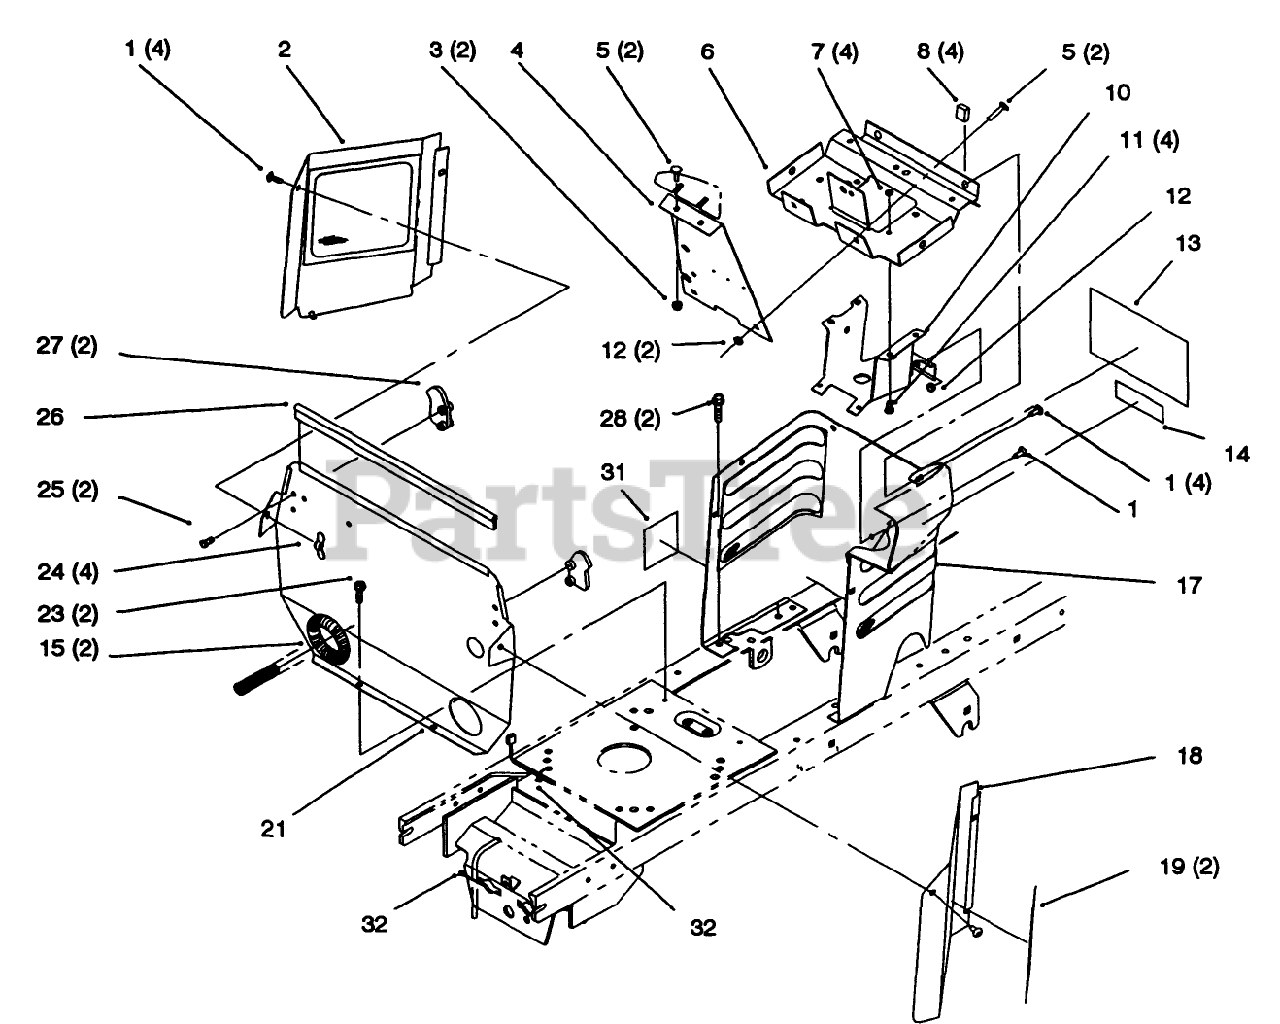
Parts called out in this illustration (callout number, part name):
1	SCREW-HH
2	RH SIDE COVER ASM
3	NUT-KEPS
4	PANEL-SUPPORT DASH
5	SCREW-CARR
6	SUPPORT-DASH
7	NUT-HEX
8	NUT RETAINER - J TYPE
10	BRACKET-COLUMN, LOWER
11	SCREW-HH
12	NUT-LOCK, NI
13	DECAL - DANGER
13	DECAL-DANGER
14	DECAL-INSTRUCTION
15	COVER-SHAFT, DRIVE
17	HOODSTAND W/DECALS
18	LH COVER ASM
19	DECAL, 264-G
19	DECAL - 264-H
19	DECAL - 266-H
21	FIREWALL
23	SCREW-HWH
24	NUT-WING
25	SCREW-PLASTITE
26	TRIM-SEAL, FIREWALL
27	LATCH-HOOD
28	SCREW-HWHTF
32	TIE-CABLE
